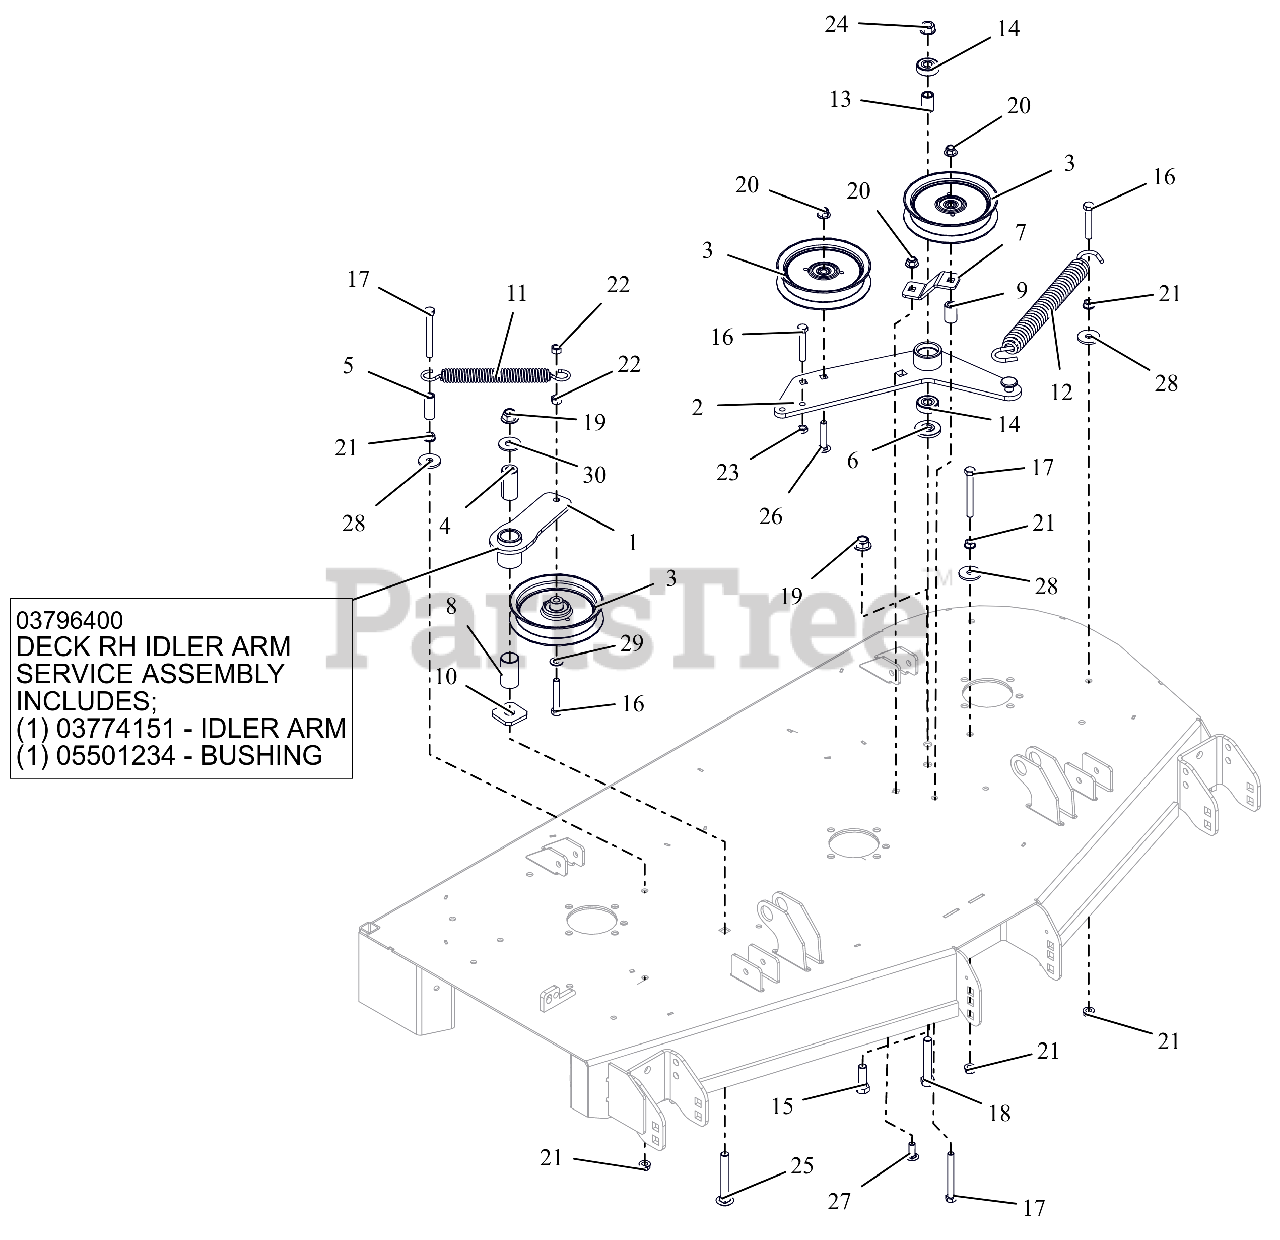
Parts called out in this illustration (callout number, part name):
1	WMT, IDLER ARM - BLACK
1	ASM, IDLER ARM (DECK)
2	DECK PTO IDLER ARM WLDMT - BLK
3	IDLER, FLAT 5.00"
4	BSHG, SPCR .502X.997X2.03 PM
5	SPACER, .375IDX.625ODX1.66 PM
6	SPACER, IDLER ARM
7	PTO FIXED IDLER MTG BRKT -RED
8	BSHG, 1.00X1.125X1.937
9	BUSHING, SLV .380X.750X1.190
10	WSHR-FLT .640X1.75X.250
11	SPRING, EXTENSION
12	SPRING, EXTENSION
13	SPACER .510 X .75 X 1.1485
14	BRG-BALL .500X1.38X.437
15	BLT,HEX .50-13X1.50 G5 ZCC
16	BLT,HEX .38-16X2.25 G5 ZCC
17	BLT, HEX .38-16X3.25 G5 ZCC
18	BLT, HEX .50-13X3.00 G5 ZCC
19	NUT,NYL-FLG .50-13 GF ZCC
20	NUT,NYL-FLG .38-16 GF ZCC
21	NUT, SPNLK-FLG .38-16 G5 ZCC
22	NUT-LK-CTR .38-16 ZC120
23	NUT-JAM .375-16 G2 ZCC
24	NUT-LK-CTR-FLG .500-13 GG ZCC
25	BLT, RHSN .50-13X3.50 G5 ZCC
26	BLT,RHSSN.375-16X2.00 G5 ZCC
27	BLT,RHSSN .38-16X1.00 G5 ZCC
28	WSHR,FLT .406X1.375X.135 ZCC
29	WSHR,FLT .406X.812X.065 ZCC
30	WSHR,FLT .563X1.375X.109 ZCC
